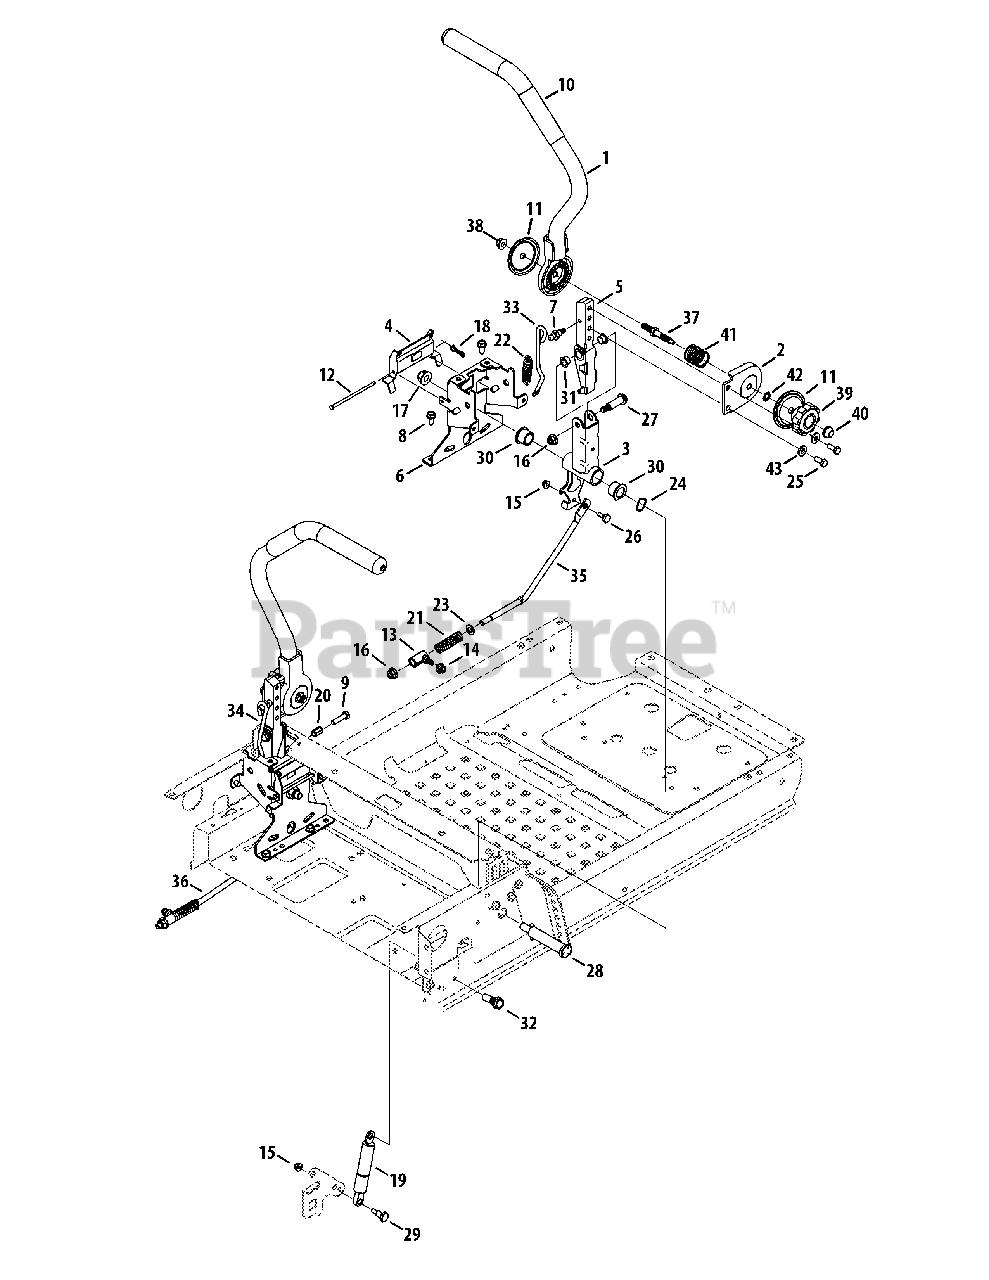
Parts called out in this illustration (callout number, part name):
1	Lapbar Lever Assembly, Otr
2	Lapbar lever Assembly, Inr
3	Lapbar Pivot Bracket
4	Brake Lever Actuator
5	Lower Arm
6	Lapbar Pivot Support Bracket
7	Screw, Shoulder Ball, 5/16-18 x .48
8	Hex Washer Screw, 5/16-18 x .750
9	Hex Cap Screw, 5/16-18 x 1.25
10	Lapbar Grip
11	Cup Adjustment Bracket
12	Pin, .188 x 4.1
13	Ferrule, 3/8 ID x .420 Shldr
14	Flange Lock Nut, 5/16-18
15	Flange Lock Nut, 1/4-20
16	Flange Lock Nut, 3/8-16
17	Flange Lock Nut, 1/2-13
18	Bow-Tie Cotter Pin
19	Dampener, .87 OD x 7.06 Lg
20	Nut, 5/16-18
21	Compression Spring, .45 x 3.215
22	Extension Spring, .56 x 2.31 x .105
23	Flat Washer, .385 x .62 x .063
24	Washer, Wave, .785 x 1.0 x .012
25	Hex Head Screw, 5/16-18 x .75 Patch
26	Shoulder Screw, .375 Dia. x .181
27	Shoulder Screw, .498 Dia. x 1.296
28	Shoulder Screw, .75 x 3.25 x 1/2-13
29	Shoulder Screw, .395 Dia. x .56
30	Bearing, .75 x 1.00 x .73
31	Flange Bearing, .500 x .627
32	Shoulder Screw, .395 Dia. x .83
33	Lapbar Detent Rod, RH
34	Lapbar Detent Rod, LH
35	Hydro Control Rod, RH
36	Hydro Control Rod, LH
37	Adjustment Stud
38	Jam Lock Nut, 3/8-16
39	Fluted Knob, 3/8-16
40	Push Cap, .250
41	Compression Spring, 1.245 x 1.275
42	Lock Washer, 3/8
43	Flat Washer, .344 x .750 x .120
